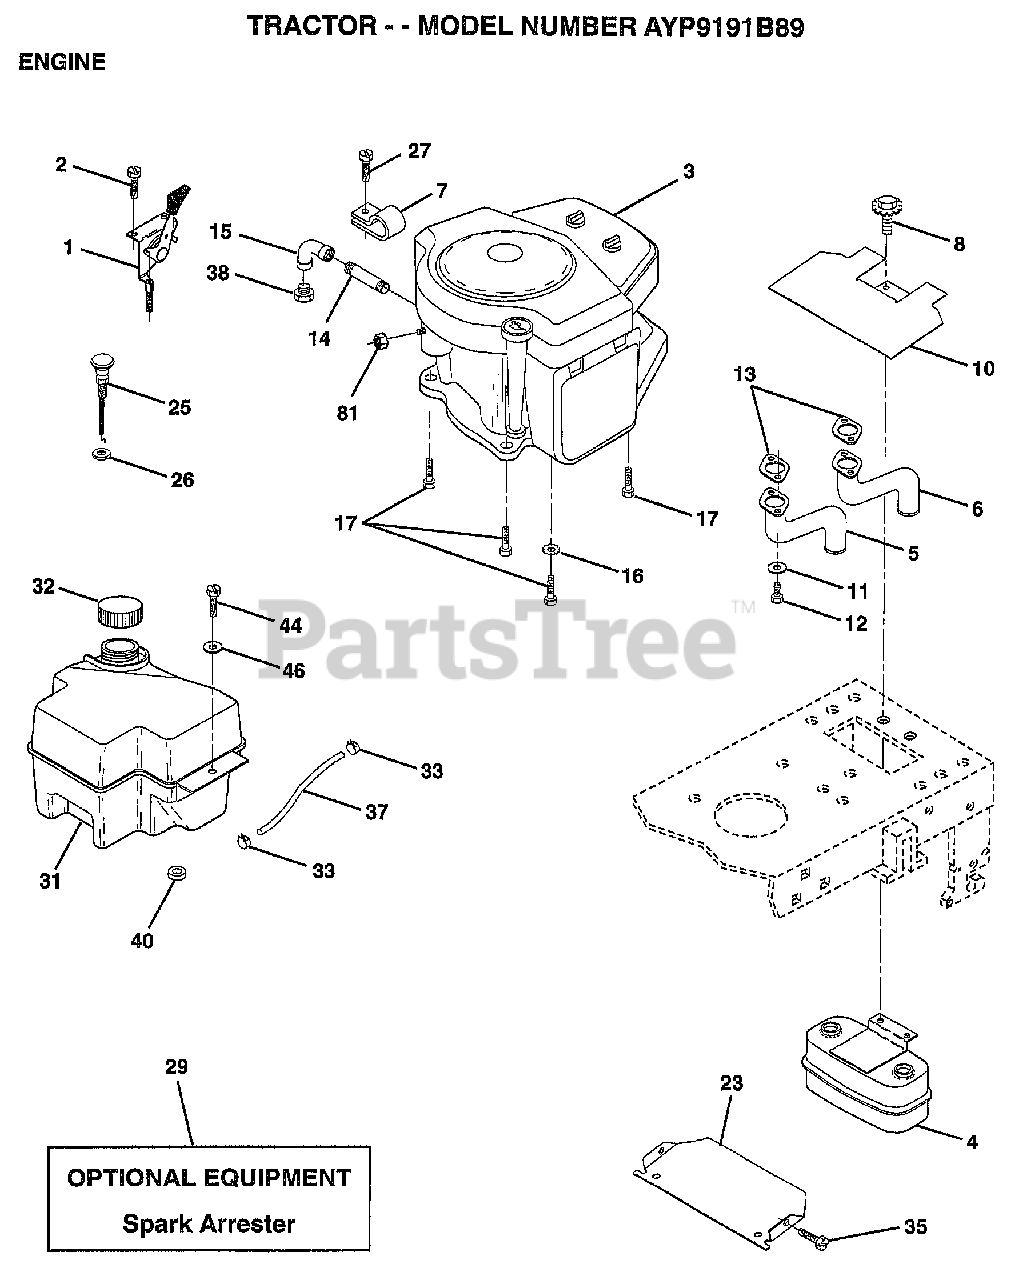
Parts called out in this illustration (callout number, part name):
1	CONTROL THRT 35.5
2	SCREW LT
4	MUFFLER.TW.LOTONE
5	EXHAUST.B&S.18.LH
6	EXHAUST.B&S.18.RH
7	CLAMP.TUBE.DBL.EN
8	BOLT.5/16-18.UNC
10	SHIELD.HEAT.
11	LOCKWASHER
13	GASKET MUFFLER
14	PIPE NIPPLE LT
15	ELBOW
16	LOCKWASHER
17	SCREW LT
23	SHIELD.BRN/DBR.GD
25	CONTROL.CHOKE.37
26	"NUT,KEPS 3/8-24IM"
27	"SCREW-TT,10-32 FL"
31	TANK.FUEL.FRONT.
32	CAP ASM FUEL
33	HOSE CLAMP
35	SCREW
37	LINE FUEL
44	SCREW HEX CRT
46	WASHER
81	NUT
